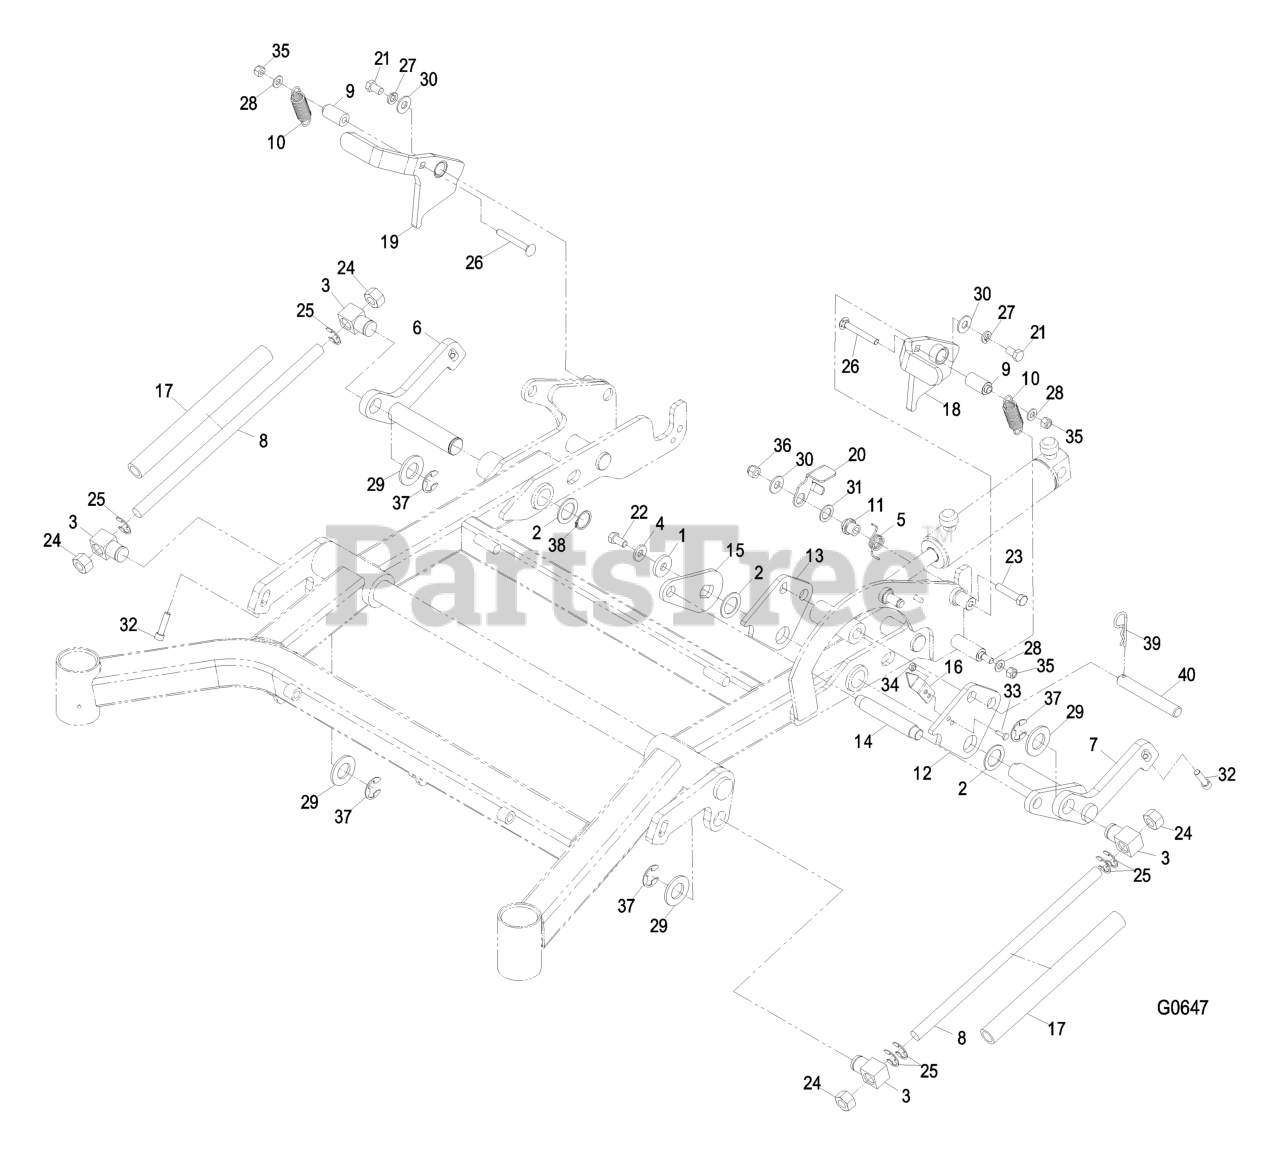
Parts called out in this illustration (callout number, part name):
2	WASHER-SPACER
3	SWIVEL-DECK MOUNT, REAR
4	WASHER-BELLEVILLE
6	WLD,DECKLIFT ARM
7	WLD,DECKLIFT ARM
8	ROD,FMZ DECKLIFT (PLATED)
9	SPACER,SPRING ANCHOR
10	SPRING-EXTENSION
11	BUSHING-LATCH, SEAT
14	PIN,DECKLIFT STOP
15	ARM,DECK LIFT
16	ARM,HEIGHT INDICATOR
17	TUBE,DECKLIFT ROD
18	WLD,LOCK LEVER LH (PLTD)
19	WLD,LOCK LEVER RH (PLTD)
20	ARM,PTO SWITCH (PLTD)
21	SCREW-HH
22	SCREW-HH
23	SCREW-HH
24	NUT-HEX
26	SCREW-CARR
27	WASHER-LOCK
28	WASHER-PLAIN
29	WASHER-FLAT
30	WASHER-FLAT
31	WASHER-FLAT
32	SCREW-HSH
33	SCREW-PPH
34	NUT-LOCK, NI
35	NUT-LOCK, NI
36	NUT-LOCK, NI
37	RING-RETAINING, EXT
38	RING-RETAINING
39	PIN-COTTER
40	PIN,CYLINDER MOUNT
